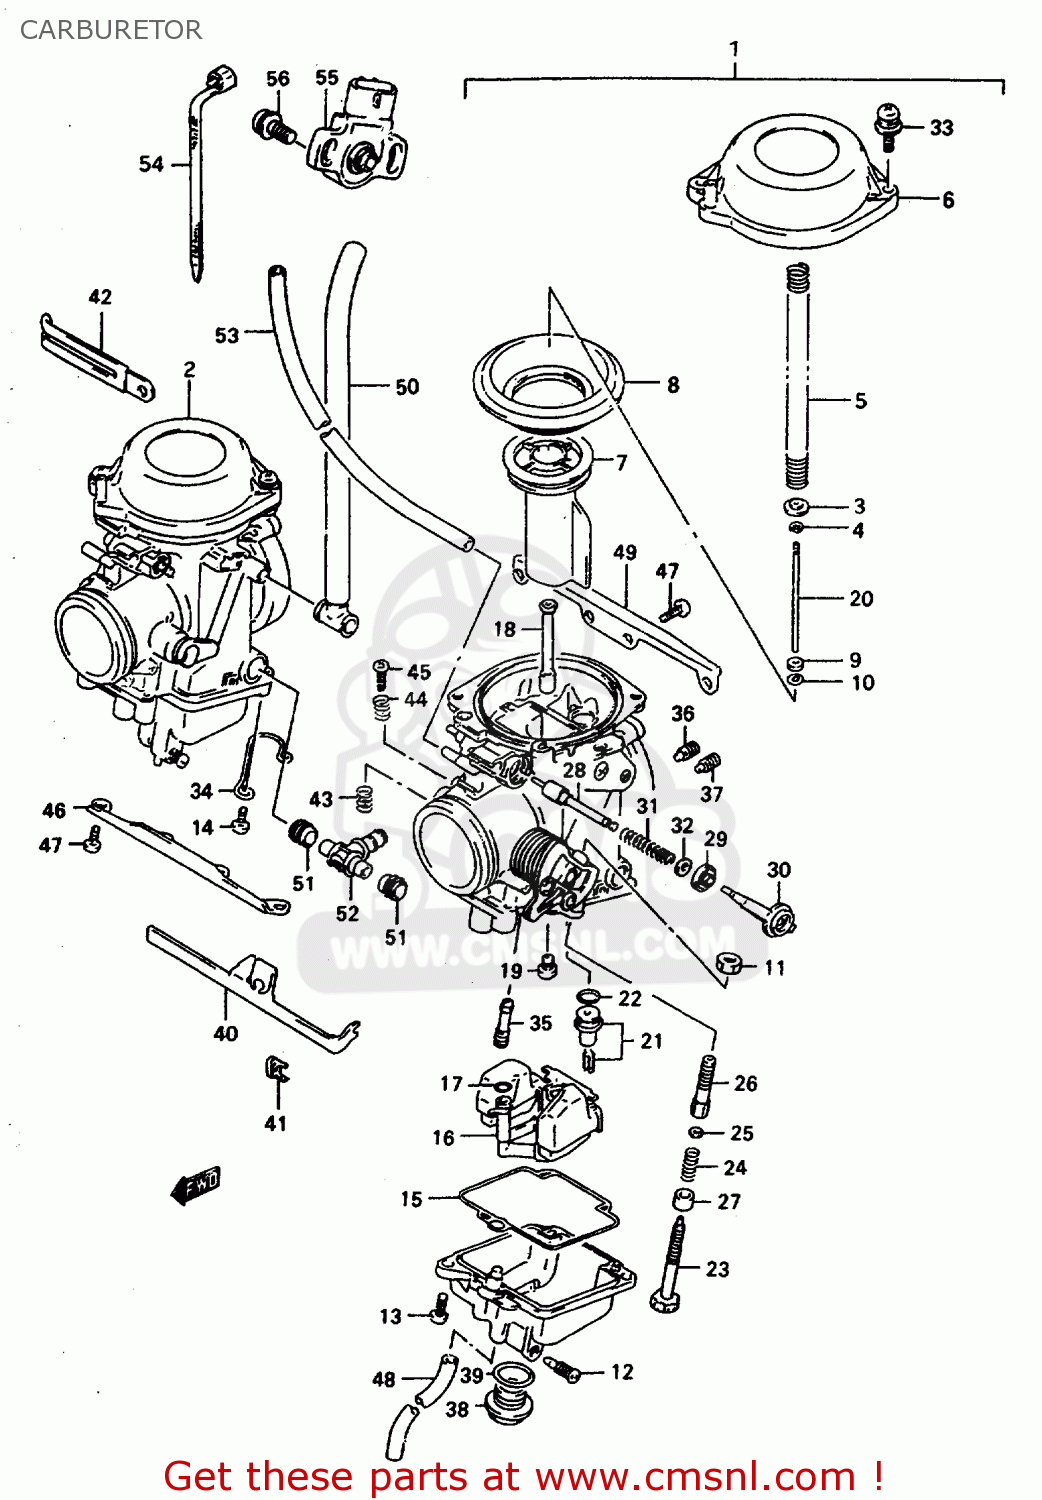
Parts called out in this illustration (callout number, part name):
1	CARBURETOR ASSY, LH
2	CARBURETOR ASSY, RH
3	RING
4	CLIP
5	SPRING
6	COVER,DIAPHRAGM
7	VALVE PISTON
8	DIAPHRAGM
9	RING
10	WASHER
11	NUT
12	SCREW,DRAIN
13	SCREW
14	SCREW(5X14)
15	GASKET,FLOAT CHAMBER (NAS)
16	FLOAT ASSY
17	O RING
18	JET,NEEDLE (O-3)
19	JET,MAIN(130)
20	NEEDLE,JET
21	VALVE ASSEMBLY,NEEDLE
22	O-RING,NEEDLE VALVE
23	ADJUSTER
24	SPRING
25	WASHER,STARTER SHAFT
26	ADJUSTER
27	RING
28	PLUNGER ASSY
29	CAP,STARTER
30	HOLDER,GUIDE
31	SPRING
32	WASHER
33	SCREW
34	CLIP
35	JET,PILOT(45)
36	JET,AIR
37	JET,AIR(0.6)
38	SCREW,GUIDE
39	O RING,DRAIN PLUG
40	LEVER,STARTER
41	HOLDER
42	CLAMP(L:65)
43	SPRING,THROTTLE SCREW
44	SPRING
45	SCREW
46	PLATE
47	SCREW
48	HOSE(3X7X600)
49	PLATE
50	HOSE
51	SEAL
52	NIPPLE
53	HOSE(5X10X600)
54	CLAMP(L:95)
55	SENSOR ASSY,THROTTLE
56	SCREW,SENSOR
